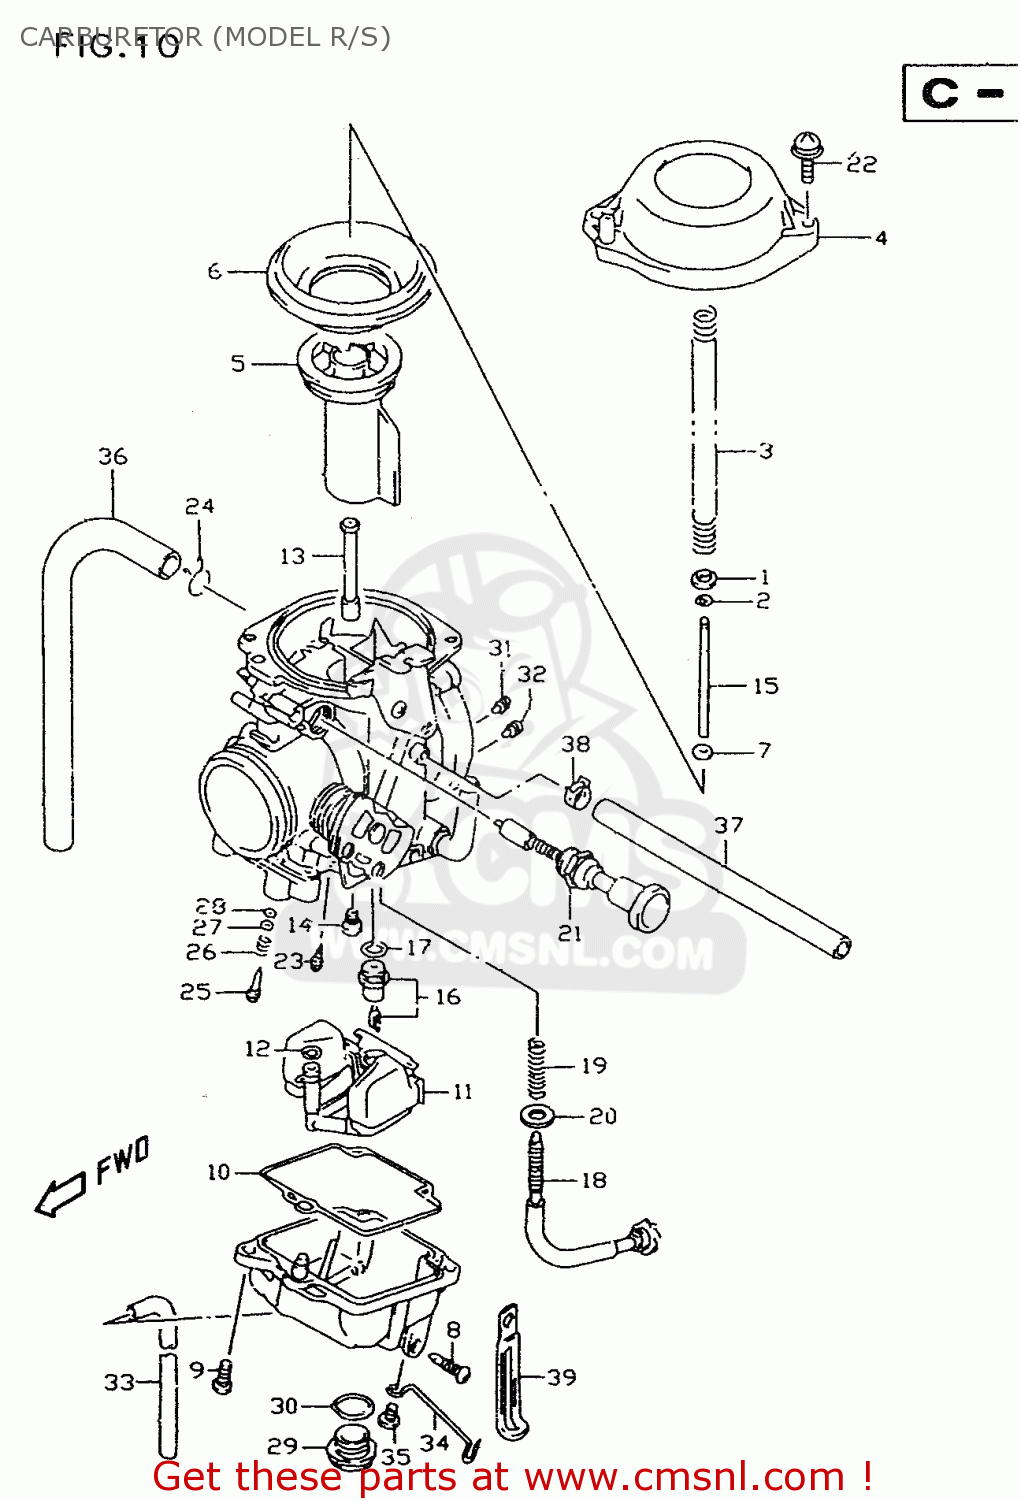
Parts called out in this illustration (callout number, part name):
1	RING
2	E RING
3	SPRING
4	COVER,DIAPHRAGM
5	VALVE PISTON
6	DIAPHRAGM
7	RING
8	SCREW,DRAIN
9	SCREW
10	GASKET,FLOAT CHAMBER (NAS)
11	FLOAT ASSY
12	O RING
13	JET,NEEDLE(O-7)
14	JET,MAIN(135)
15	NEEDLE,JET
16	VALVE ASSEMBLY,NEEDLE
17	O-RING,NEEDLE VALVE
18	ADJUSTER
19	SPRING,THROTTLE SCREW
20	WASHER,STARTER SHAFT
21	PLUNGER ASSEMBLY
22	SCREW
23	JET,PILOT(42.5)
24	CLIP
25	SCREW,PILOT
26	SPRING
27	WASHER
28	O RING,PILOT AIR SCREW
29	SCREW,GUIDE
30	O RING,DRAIN PLUG
31	JET,AIR(1.3)
32	JET,AIR(0.6)
33	HOSE(3X5X600)
34	CLIP
35	SCREW
36	HOSE(7X11X600)
37	HOSE(5X8.2X600)
38	CLIP
39	CLAMP
